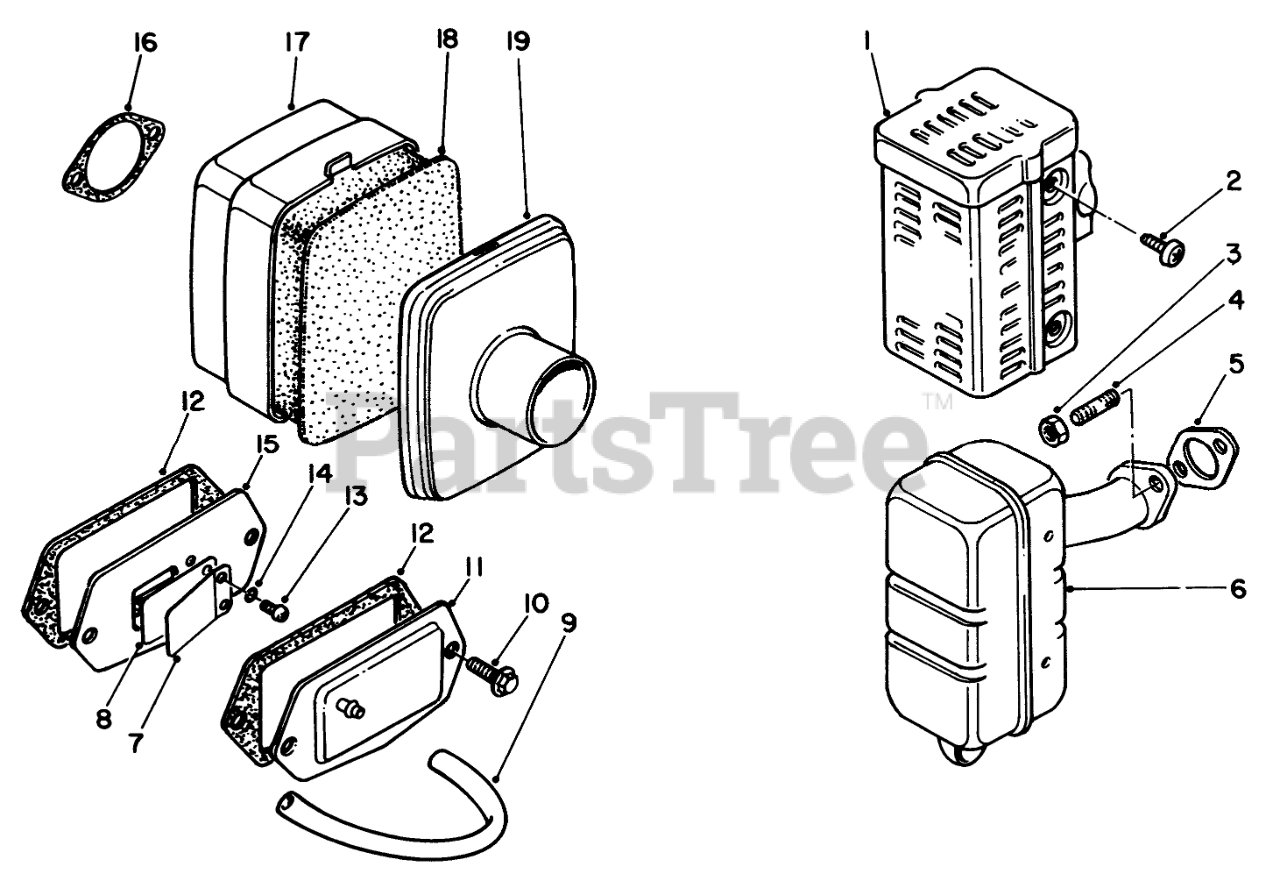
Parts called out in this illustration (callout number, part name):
1	Cover-Muffler
2	Screw-Round Phillips Hd.
4	Stud Bolt
5	Gasket-Exhaust
6	Muffler
7	Stopper
8	Reed Valve
11	Cap-Breather
12	Gasket
13	Screw
14	Lockwasher
15	Reed Valve Assembly (Incl. Ref. #7, 8, 13 & 14)
16	GASKET-AIR CLEANER
17	Air Cleaner Assembly (Incl. Ref. #19)
18	AIR CLEANER FILTER
